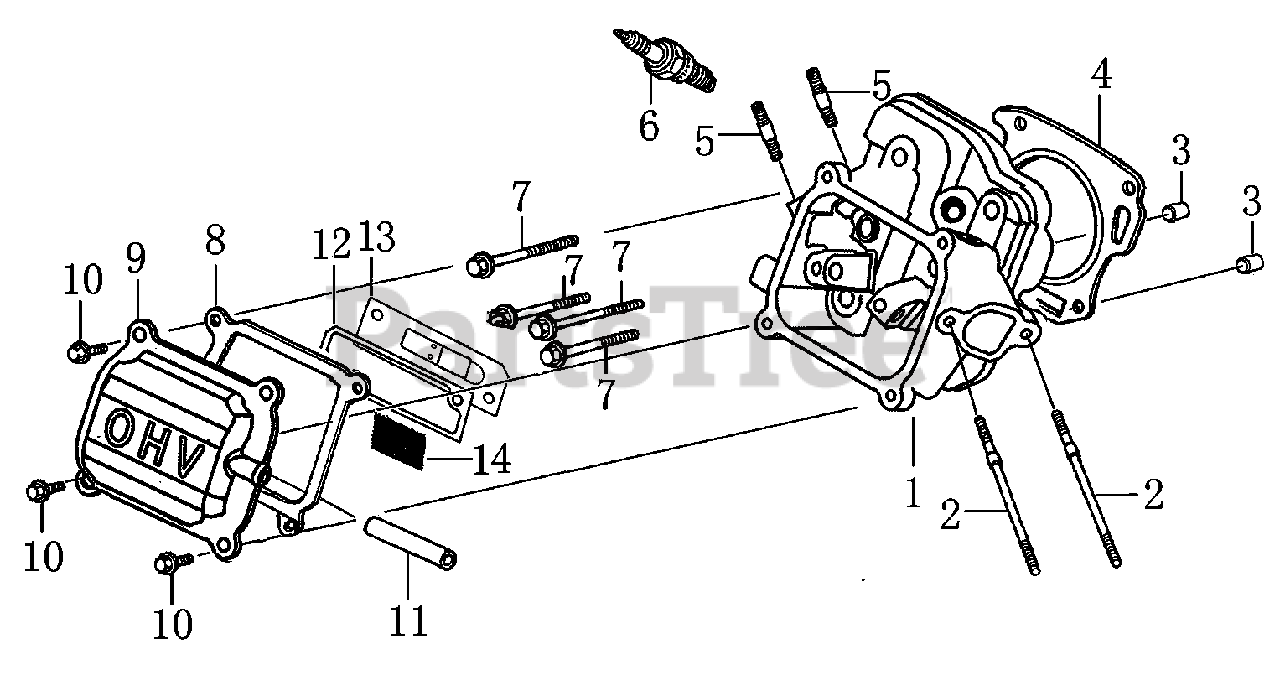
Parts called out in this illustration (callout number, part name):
1	HEAD, CYLINDER
2	STUD BOLT, INTAKE
3	PIN, DOWEL
4	GASKET, CYLINDER HEAD
5	BOLT, STUD, EXHAUST
6	PLUG, SPARK
7	BOLT, FLANGE
8	GASKET, VALVE COVER
9	COVER, VALVE
10	BOLT, FLANGE
11	TUBE, BREATHER
12	GASKET, BREATHER CHAMBER
13	CAP, BREATHER CHAMBER
14	STRAINER, OIL
